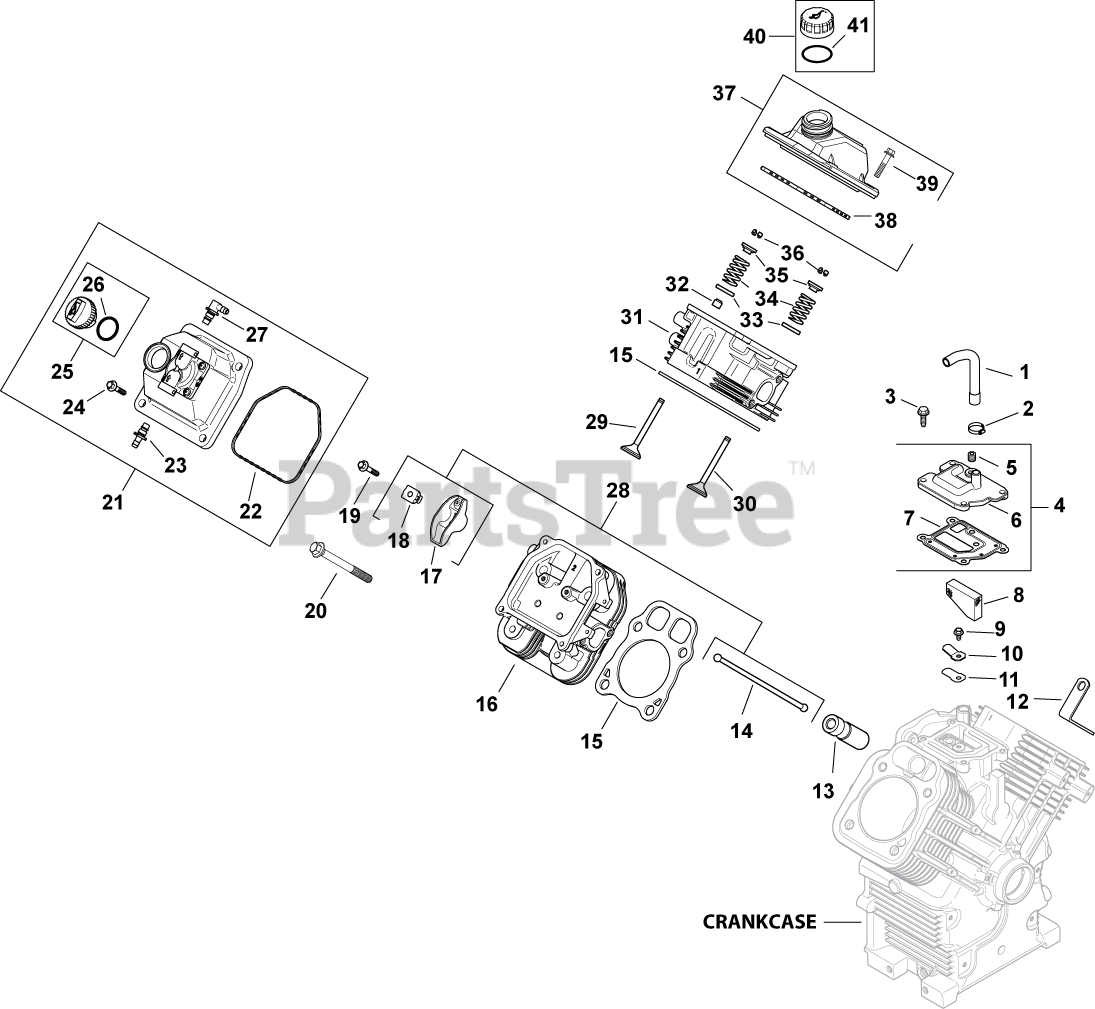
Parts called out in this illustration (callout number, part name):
1	HOSE, BREATHER
2	CLAMP, HOSE (KM)-USE 25 237 31-S
3	SCREW,FLG THD FRM M6X1.0X20-(#25086396S)
4	KIT, BREATHER ASSEMBLY
5	PLUG, CTSK PIPE 1/8"
6	COVER, BREATHER -USE 24 033 01-S
7	GASKET, BREATHER-USE 24 041 67-S
8	FILTER, BREATHER
9	SCREW, FLG THD FRM M5X.8X10
10	RETAINER, REED
11	REED, BREATHER
12	STRAP, LIFTING-USE 25 445 03-S
13	LIFTER, HYDRAULIC VALVE-USE 25 351 10-S
14	ROD, PUSH
15	KIT, CYL HEAD GASKET (C17-22)
16	HEAD, ASSEM CYLINDER #2 -USE 24 318 115-
17	ARM, ROCKER
18	PIVOT, ROCKER ARM
19	SCREW, FLG M6X1.0X34
20	SCREW - USE 62 086 08-S
21	KIT, VALVE COVER-FUEL PUMP
22	O-RING (BLACK)
23	CONNECTOR
24	SCREW, FLG M6X1.0X30
25	CAP ASSY, OIL FILL (YELLOW)
26	O-RING-USE 24 153 32-S
27	CONNECTOR, 90 DEG. HOSE
28	KIT, VALVE TRAIN
29	VALVE, EXHAUST (STD) - USE 32 016 01-S
30	VALVE, INTAKE (STD)
31	HEAD, ASSEM CYLINDER #1 -USE 24 318 107-
32	RETAINER, SPRING
33	SEAL, VALVE STEM - (#2503214S)
34	SPRING, VALVE
35	RETAINER, VALVE SPRING - USE 25 173 28-S
36	KIT, RETAINER
37	KIT, VALVE COVER-OIL FILL
38	O-RING (YELLOW), VALVE COVER
39	SCREW, SHOULDER
40	KIT, OIL FILL CAP (YELLOW)
41	O-RING, DIPSTICK
2401602-S	VALVE, EXHAUST (.25)
2401702-S	VALVE, INTAKE (.25)
